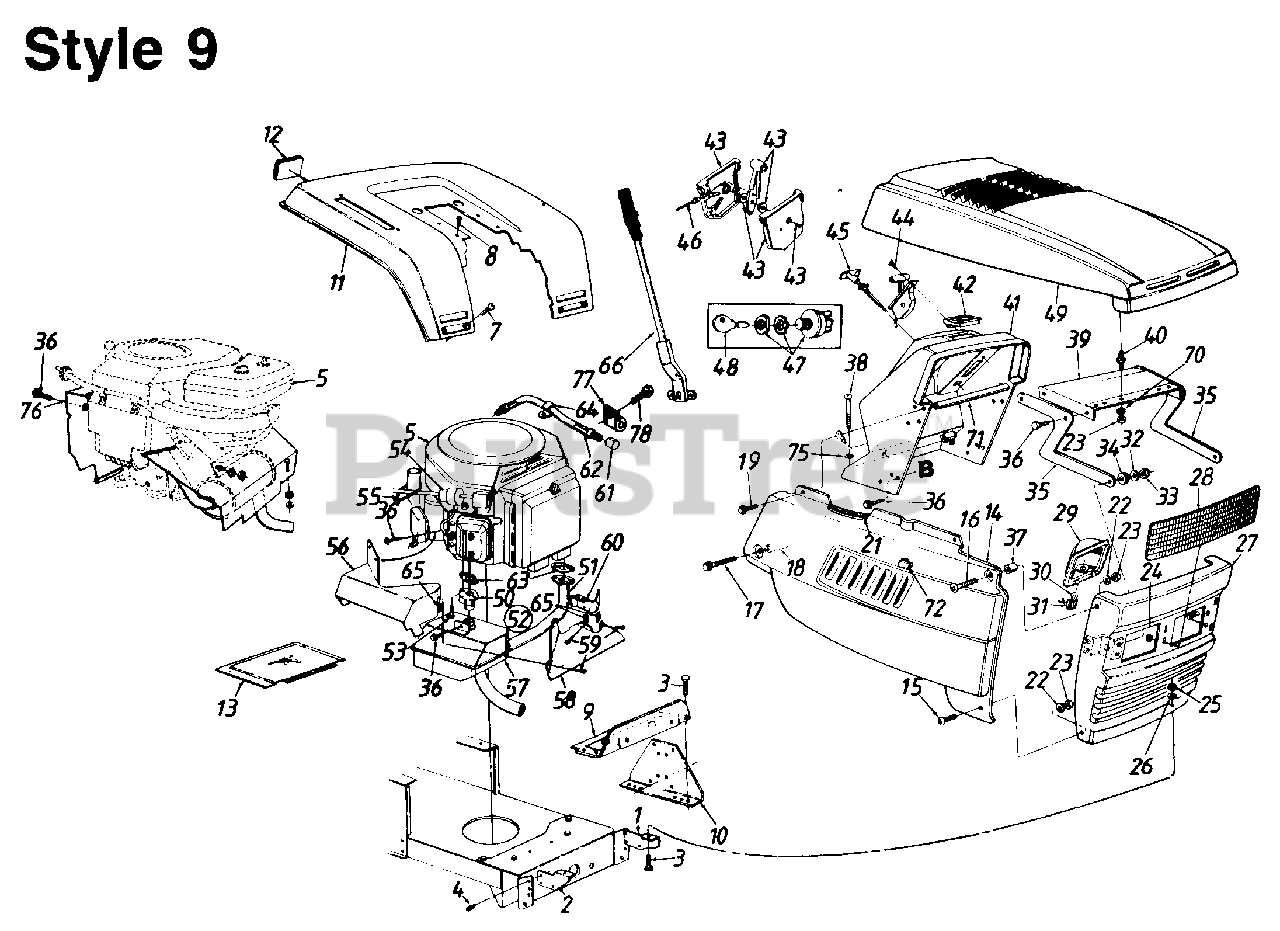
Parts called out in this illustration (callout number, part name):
1	Grille Mtg. Brkt.-L.H.
4	Hex Wash. Hd. Tap Scr. 5/16-18 x .5" Lg.
5	Engine
7	Carriage Bolt 1/4-20 x .5" Lg.
8	Hex Wash. Hd. Tap Scr. 5/16 x .75" Lg.
9	Support Bracket
10	Dash Support Bracket
13	Transmission Cover
14	Side Panel-R.H.
15	Truss Mach. Scr. 1/4-20 x .5" Lg.
16	Truss Mach. Scr. 1/4-20 x 1.0" Lg.
17	Hex Wash. TT-Tap Scr. 1/4-20 x 1.75" Lg.
18	Spacer .26" I.D. x 1.32"
19	Hex Rolling Tap Scr. 1/4-20 x .75" Lg.
21	Trim Strip-12" Lg.
22	L-Wash. 1/4" I.D.
23	Hex Nut 1/4-20 Thd.
24	Speed Nut 5/16" Thd.
25	Hex Nut 5/16-18 Thd.
26	L-Wash. 5/16" I.D.
29	Headlamp Housing
30	Headlamp
31	Twist Lock Lamp Socket
32	Bell-Wash. .345" I.D. x .88"
33	Hex L-Nut 5/16-18 Thd.
34	Rubber Washer
35	Hood Hinge
36	Hex Wash. Hd. B-Tap Scr. 1/4-20 x .5" Lg.
37	Spacer .265" I.D. x .376"
38	Mach. Scr. 1/4-20 x 1.5" Lg.
39	Hood Plate
40	Double Ended Stud 1/4-20 Thd.
42	Ammeter
43	Throttle Control Box Ass'y.
44	Mach. Scr. #10 x .44" Lg.
45	Choke Control
46	Throttle Control Wire
47	Ignition Switch
48	Ignition Key
50	Inlet Tube Ass'y.
51	Formed Tube Ass'y.
52	Muffler Ass'y. Comp.
53	Hex Bolt w/Washer
54	Hose Clamp .406" Dia.
55	Cable Tie
56	Muffler Heat Shield
57	Exhaust Muffler Sub Ass'y.
58	Front Heat Shield
59	Hex AB-Tap Scr. #10 x .5" Lg.
60	Front Heat Shield Ext.
61	Cap Oil Drain
62	Oil Drain
63	Exhaust Gasket
64	Clamp
65	Speed Nut #10-24 Thd.
66	Lift Handle
70	Bell-Wash. .265" I.D. x .75"
71	Grille Support Tube
72	Mounting Clamp
75	Retaining Nut
76	Baffle w/Trim Strip
77	Clamp
78	Hex Bolt M6 x 17MM
